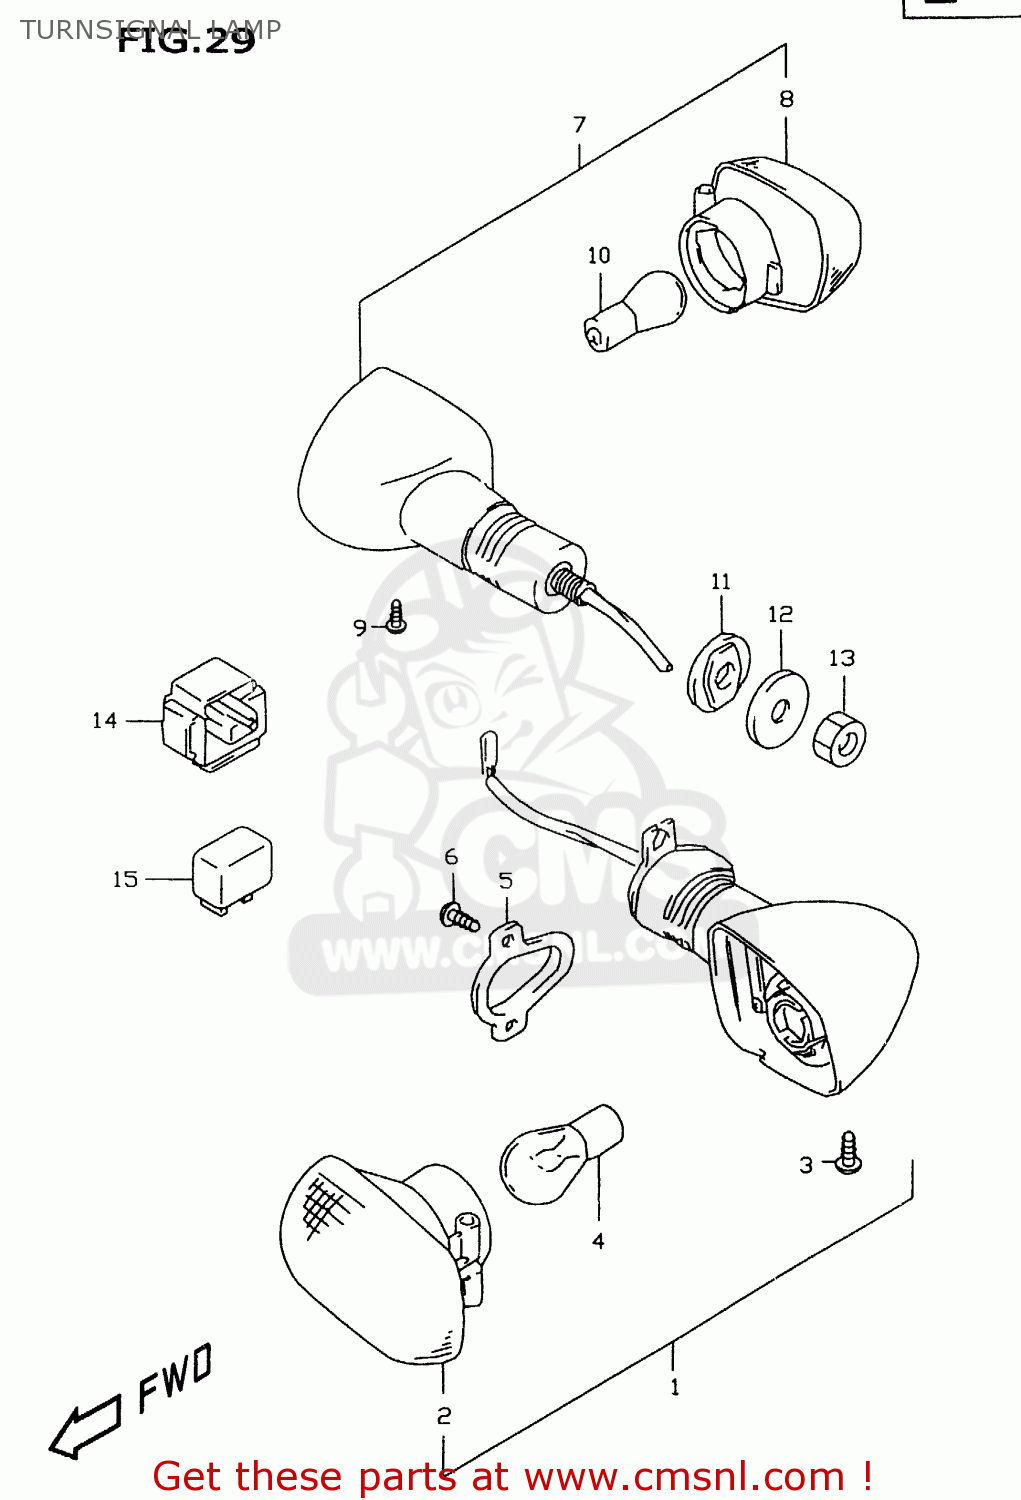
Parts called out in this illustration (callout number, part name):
1	LAMP ASSEMBLY,FRONT TURN SIGNAL
2	LAMP UNIT
3	SCREW
4	BULB(12V21W)
5	PLATE,FR TURNSIGNAL LAMP
6	SCREW
7	LAMP ASSY,RR TURNSIGNAL,R
8	LAMP UNIT
9	SCREW
10	BULB(12V21W)
11	SPACER,RR TURNSIGNAL
12	WASHER(10.5X30X2.3)
13	NUT
14	RELAY ASSY
15	RELAY ASSY,TURNSIGNAL LAMP
